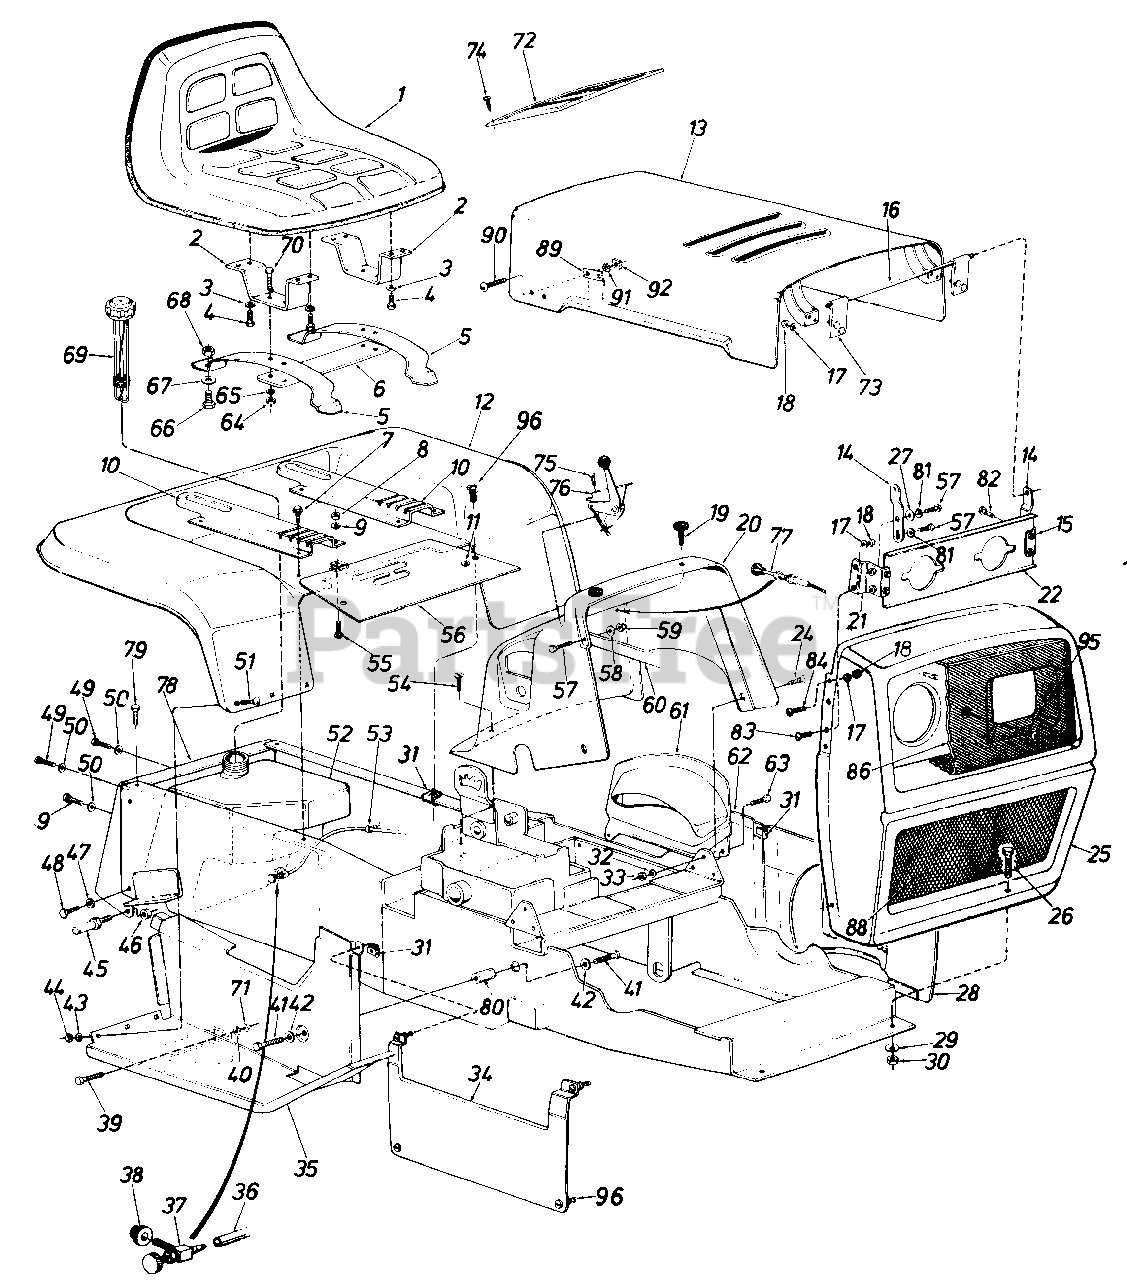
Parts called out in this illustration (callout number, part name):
1	Seat Ass'y. Comp.
2	Seat Brkt.
3	L-Wash. 3/8" Scr.
4	Hex Scr. 3/8-16 x .75" Lg.
7	Hex Wash. Hd. Self-Tap Scr. 5/16-24 x .75" Lg.
8	Hex Nut 5/16-18 Thd.
9	L-Wash. 5/16" Scr.
10	Seat Adjuster Brkt.
11	Snap Bushing
12	Rear Fender Ass'y.
13	Hood Ass'y.
16	Hinge Rod
17	L-Wash. 1/4" Scr.*
18	Hex Nut 1/4-20 Thd.
19	Rubber Bumper
20	Instrument Panel
21	Hood Support Brkt. Ass'y.-R.H.
27	Fl-Wash. .25 I.D. x 1.25 O.D.
28	Panel Ass'y.-L.H.
29	Belleville Wash.
30	Hex Nut 5/16-18 Thd.
31	U-Type Speed Nut
32	L-Wash. 1/4 " Scr.
33	Hex Nut 1/4-20 Thd.
34	Panel-R.H.
35	Foot Step Panel-R.H.
36	Gas Hose 3/16" I.D. x 5/16" O.D. x 72" Lg.
37	Fuel Shut-Off Valve
38	Rubber Bushing
39	Hex Scr. 3/8-16 x 1.00" Lg. (Grade 5)
40	L-Wash. 3/8" Scr.
41	Hex Scr. 3/8-16 x .62" Lg.
42	Fl-Wash. .385 I.D. x .62 O.D.
43	L-Wash. 1/4" Scr.
44	Hex Nut 1/4-20 Thd.
45	Link Clevis Pin
46	Hex Cent. L-Nut 5/8-18 Thd.
47	L-Wash. 818" Scr.*
48	Hex Scr. 3/8-24 x 1.00" Lg. (Grade 5)
49	Hex Scr. 1/4-20 x .62" Lg.*
50	Bell-Wash.
51	Carr. Bolt 1/4-20 x .50" Lg.*
52	Fuel Tank
53	Tie Strap
54	Flat Hd. Self-Tap Scr. 1/4 " Dia. x .62" Lg.
55	Carr. Bolt 5/16-18 x .62" Lg.*
56	Transmission Cover
57	Hex Scr. 1/4-20 x .75" Lg.*
58	L-Wash. 1/4" Scr.*
59	Hex Nut 1/4-20 Thd.*
60	Grille Strap
61	Instrument Panel Insert
62	Foot Step Panel-L.H.
63	Thread Rol li ng Scr. 1/4"
64	Hex Nut 5/16-18 Thd.*
65	L-Wash. 5/16" Scr.*
66	Nylon Scr. 1/2-13 x .75" Lg.
67	Fl-Wash. 1/2" I.D.
68	Hex Cent. L-Nut 1/2-13 Thd.
69	Fuel Gauge
70	Hex Scr. 5/16-18 x .75" Lg.*
71	Hex Nut 3/8-16 Thd.*
72	Instrument Panel Cover
73	Hood Hinge Ass'y.
74	Self-Tap Black Oval Hd. Scr. 1/2" Lg.
75	Fl-Hd. Truss Scr. #10 x .62" Lg.
76	Throttle Control Ass'y.
77	Choke Control Ass'y.
80	Lift Shaft Pivot Pin
81	Bell-Wash.
82	Hex Scr. 1/4-20 x .38" Lg.*
83	Truss Hd. Scr. 1/4-20 x .50" Lg. *
84	Truss Hd. Scr. 1/4-20 x .75" Lg. *
86	Head Lamp Bezel
88	Grille Screen
89	Hood Spring
90	Truss Mach. Scr. 10-24 x 3/8"
91	L-Wash. #10
92	Hex Nut 10-24 Thd.
95	Truss Mach. Scr. #10-24 x .62" Lg.
96	Truss Mach. Scr. #10-24 x .50" Lg.
